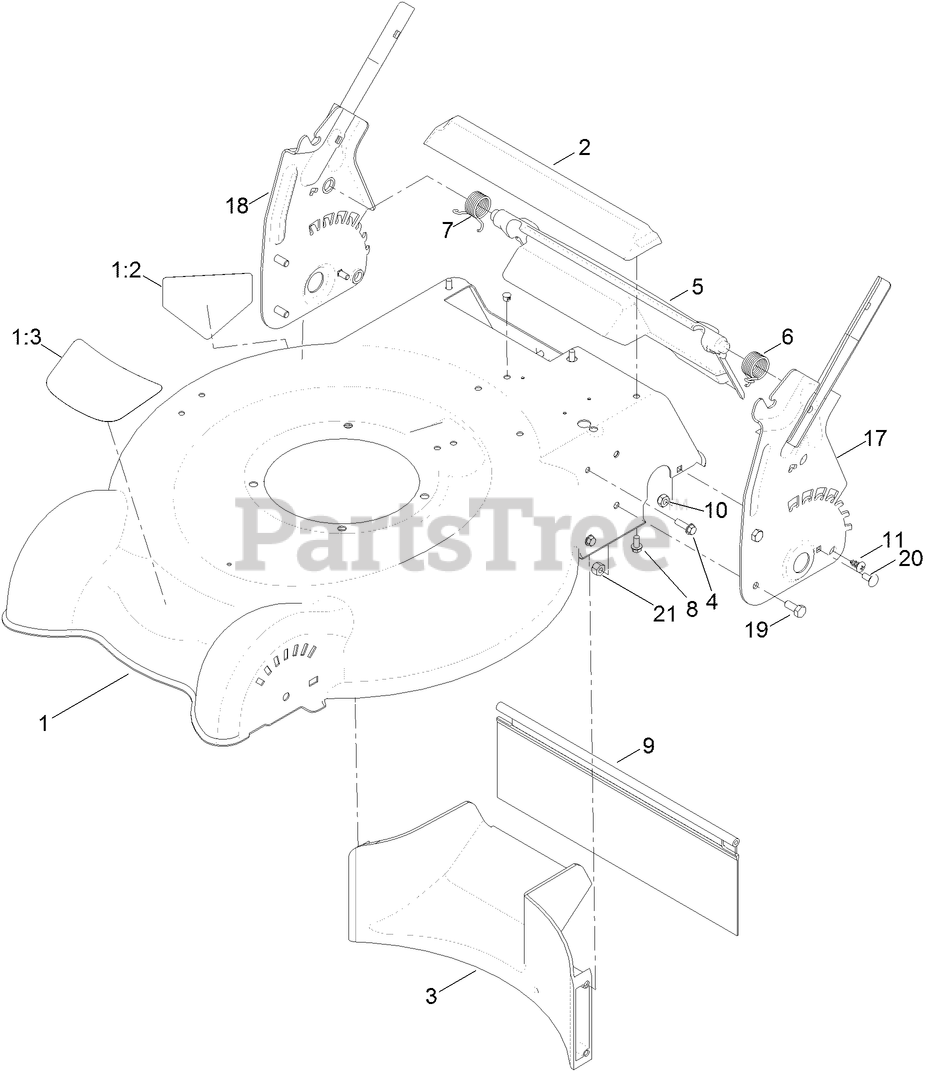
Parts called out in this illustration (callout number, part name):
1	HOUSING ASM
1:2	DECAL-DANGER
1:3	DECAL-DECK
2	CHUTE-REAR
3	BAFFLE-REAR
4	SCREW-HWH
5	REAR DEFLECTOR ASM
6	SPRING-TORSION, LH
7	SPRING-TORSION, RH
8	SCREW-PLASTITE
9	SHIELD-TRAILING
10	NUT-LOCK, NI
11	SCREW-PTH
19	SCREW-HH
20	SCREW-CARR
21	NUT-LOCK, NI
